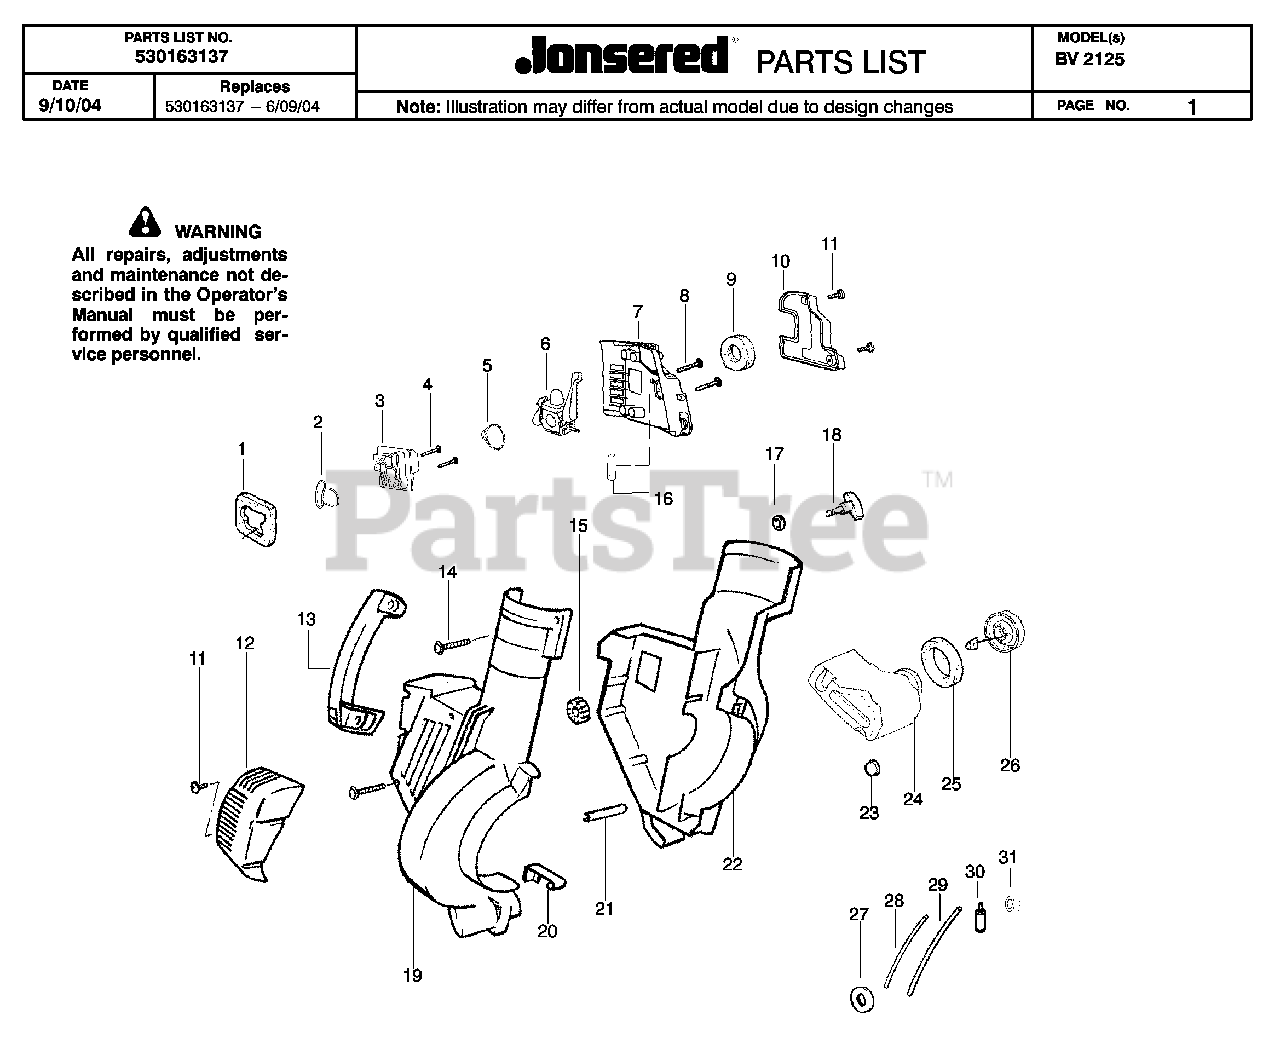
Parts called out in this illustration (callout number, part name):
2	GASKET KIT
5	GASKET KIT
6	CARB
6	KIT CARB ASSY C1Q-W11
11	SCREW FILTER PLATE
14	SCREW-10-14 X 13/16 (PL
23	CRANKCASE ISOLATOR
30	FUEL PICK-UP ASSY
